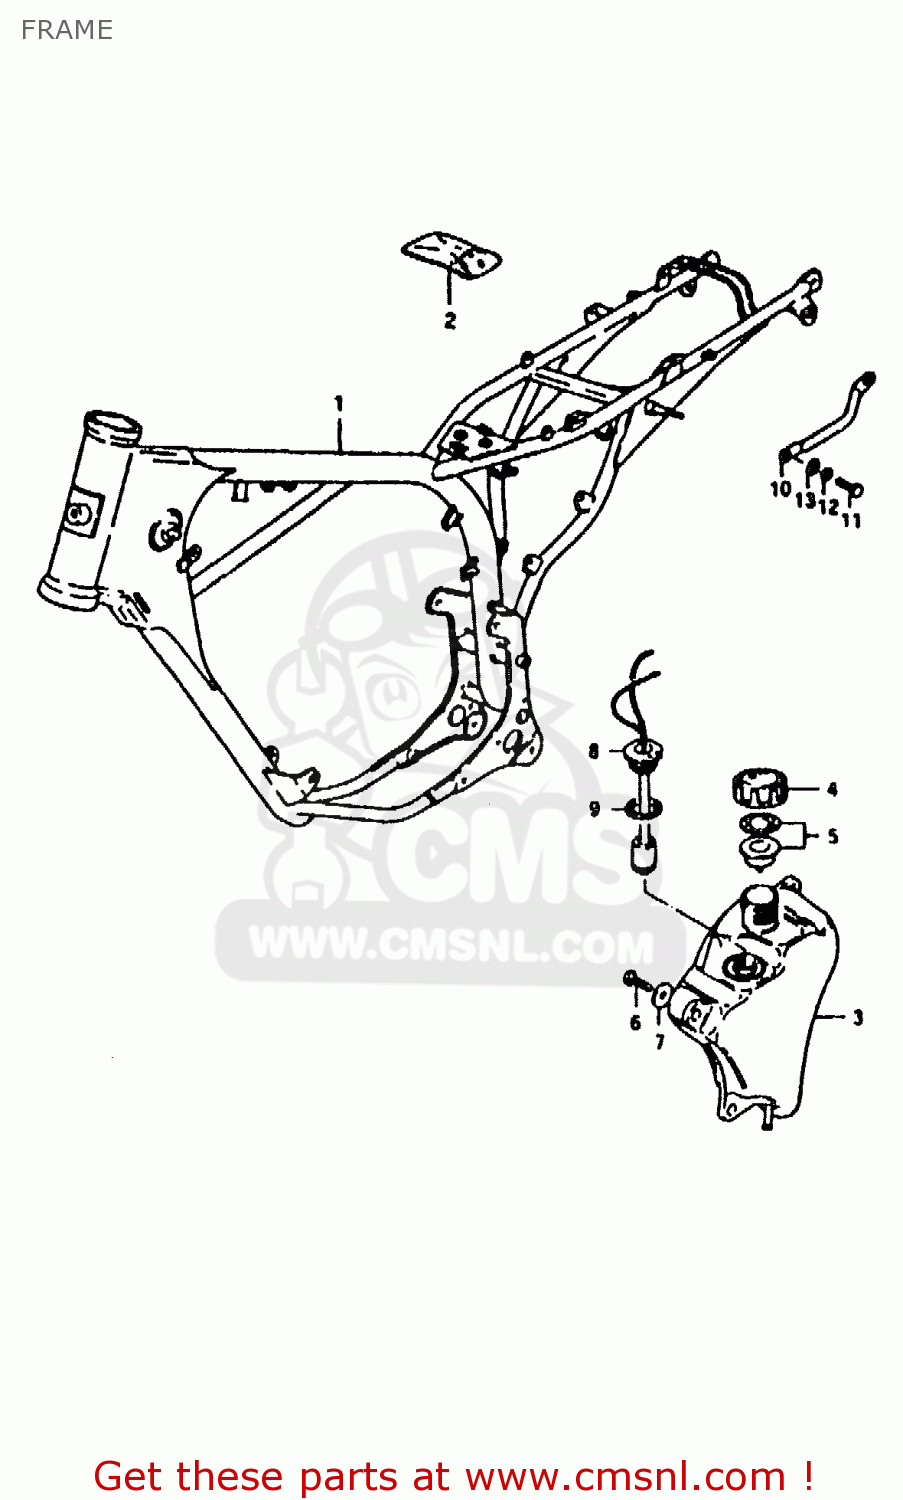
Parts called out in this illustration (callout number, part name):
1	FRAME (BLACK)
2	TOOL SET
3	TANK, OIL
4	CAP,OIL TANK
5	GASKET SET (NAS)
6	BOLT, UPPER
7	WASHER
8	SWITCH, OIL LEVEL
9	GASKET (NAS)
10	GRIP, STAND
11	BOLT
12	LOCK WASHER
13	WASHER
